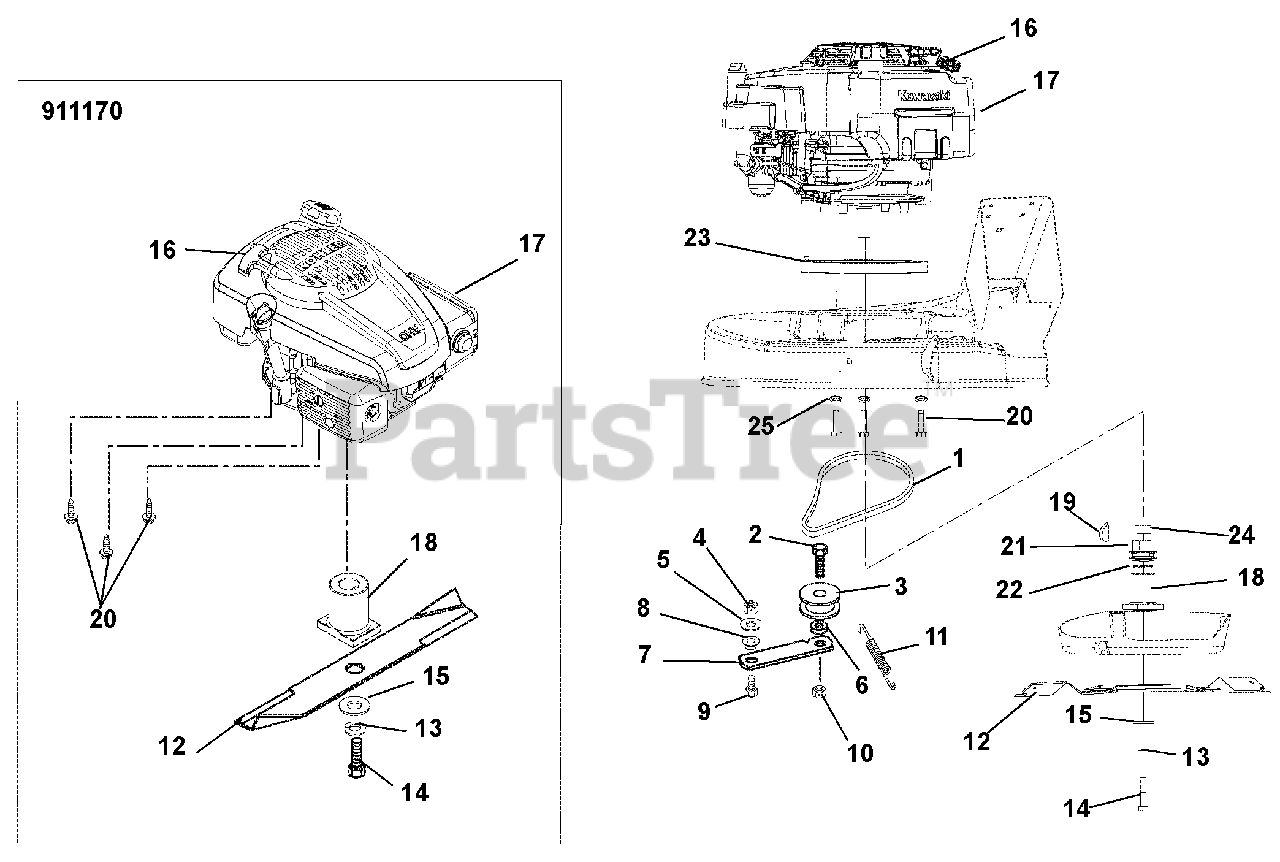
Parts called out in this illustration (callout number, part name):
1	V-Belt 3L Section (911196, 197)
2	Bolt, Hex .44-14 x 1.50 Grade 5 (911196, 197)
3	Idler, Flat 1.75 x .47 (911196, 197)
4	Nut, Locking Center .31 -18 (911196, 197)
5	Washer, Flat Steel .344 x .688 x .065 (911196, 197)
6	Bushing, Sleeve .469 x .75 x .43 (911196, 197)
7	Idler Arm (911196, 197)
8	Bushing, Flange .325 x .501 x .250 x 1.120 (911196, 197)
9	Bolt, Hex .31-18 x .75 Grade 5 (911196, 197)
10	Nut, Locking Center .44-14 (911196, 197)
11	Spring, Tension .043 x .44 x 3.31 (911196, 197)
12	Blade, 21" Mower
13	Washer, Locking .38 x .094
14	Bolt, Hex .38-24 x 2.00 Grade 8 (911171)
15	Washer, Flat Steel .390 x 1.50 x .125
16	Recoil Start Handle
17	Engine, Kohler XT-8 50 State (911171)
18	Adapter, Blade (911171)
19	Key, Woodruff .156 x .625 x .25 SAE #6 (911196, 197)
20	Screw, Tapping .38-16 x 1.00 Hex Washer Head (911171)
21	Pulley, Crank (911196, 197)
22	Washer, Wave .885 x 1.311 x .125 (911196, 197)
23	Plate, Engine Shim (911196, 197)
24	Spacer, .875 x 1.125 x .525 (911196, 197)
25	Spacer .75 x .515 x .12 (911196, 197)
